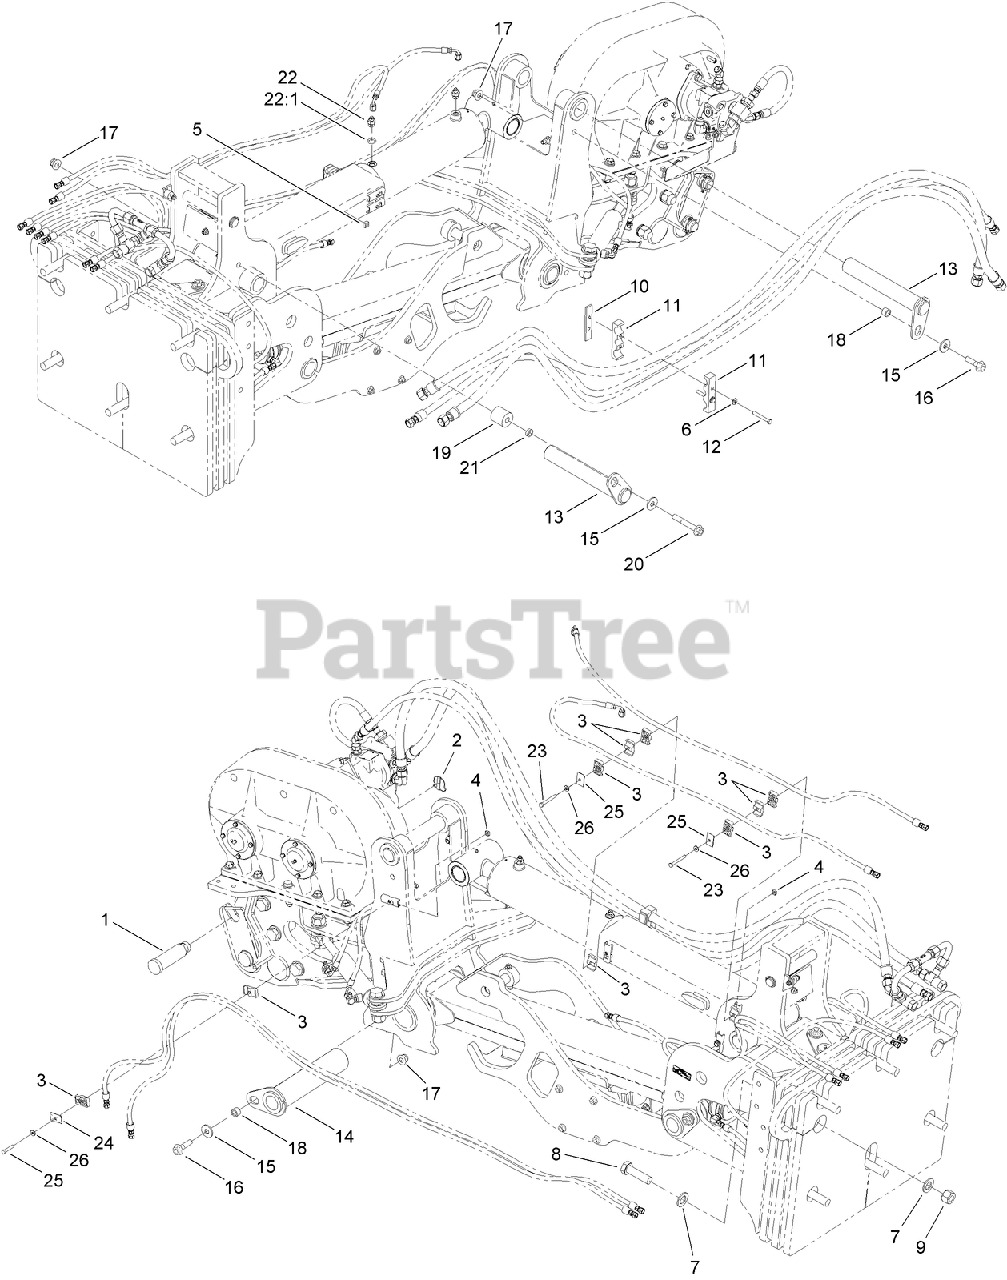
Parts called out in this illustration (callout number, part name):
1	PIN-MOUNTING, BLADE
2	PIN-KLIK
3	CLAMP-TUBE
4	NUT-SQUARE
5	NUT-SQUARE
6	WASHER-FLAT
8	SCREW-CAP, HH
11	BLOCK-CLAMP (HOSE-HYD)
12	BOLT-HH
13	PIN-FLAGGED
14	PIN-FLAGGED
15	WASHER-FLAT
16	SCREW-FLANGE
17	NUT-HHF
18	SPACER-PIN
19	SPACER
20	SCREW-FLANGE
21	SPACER-PIN
22	CONNECTOR
22:1	O-RING
23	SCREW-HH
24	COVERPLATE
25	SCREW-HH
26	Washer
